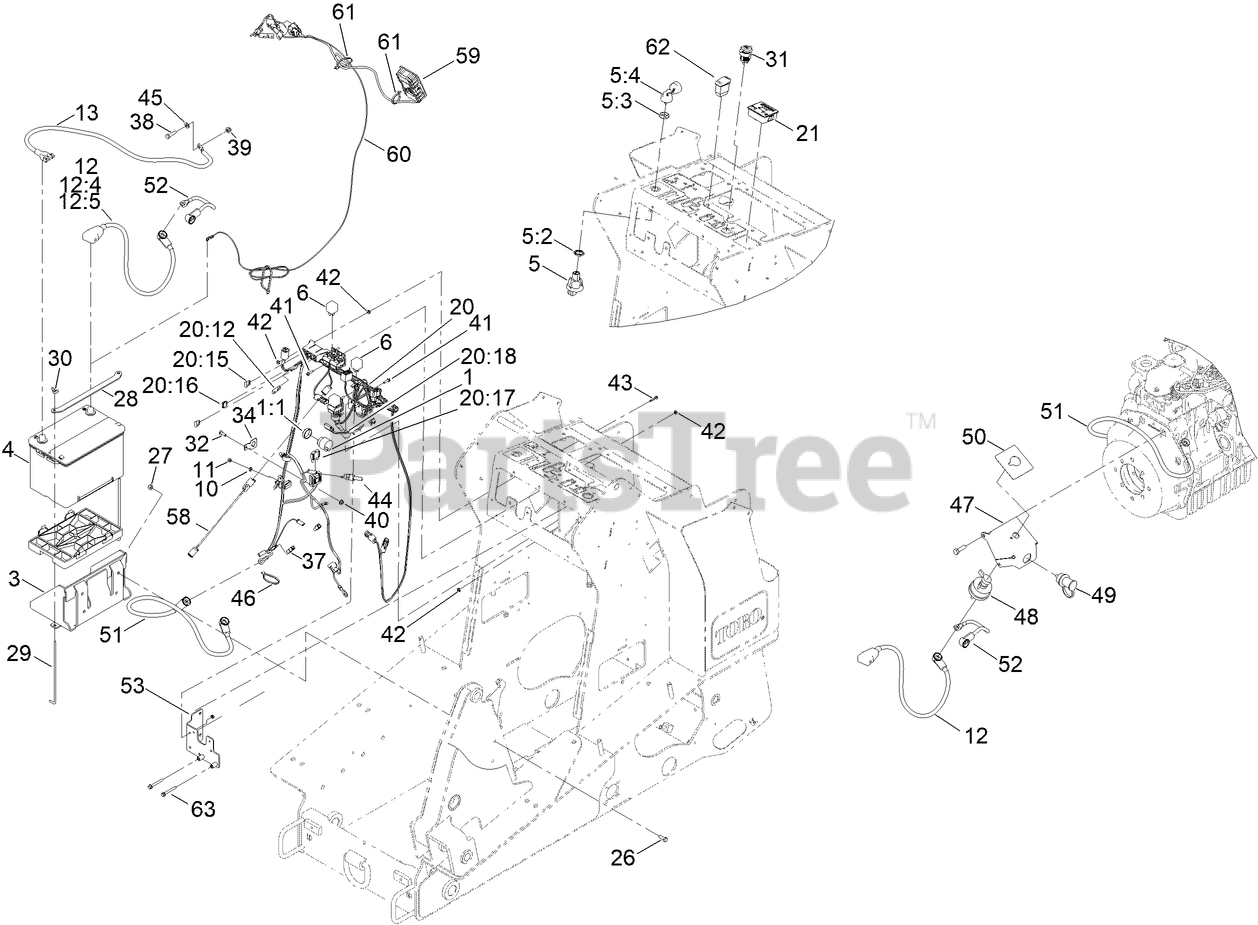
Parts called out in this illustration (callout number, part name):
1	AUDIO ALARM ASM
1:1	NUT-PLASTIC, KNURLED
3	TRAY-BATTERY
4	BATTERY
5	IGNITION SWITCH ASM
5:2	NUT-HEX
5:3	NUT-FACE
5:4	SET-KEY, IGNITION
10	WASHER-LOCK, SPRING
11	NUT-HEX
12	CABLE-BATTERY, POS ASM
12:4	BOLT-BATTERY CLAMP, 5/16-18 UNC
12:5	NUT-CLAMP, BATTERY
13	CABLE-NEGATIVE
20	HARNESS-WIRE, TX1000
20:15	FUSE-BLADE, 10 AMP
20:16	FUSE-BLADE, 15 AMP
20:17	FUSE-BLADE, 50 AMP
20:18	CAP-PLUG
21	MODULE-HOUR METER
26	SCREW-HH
27	NUT-LOCK, NI
28	STRAP-HOLD DOWN, BATTERY
29	ROD-HOLD DOWN, BATTERY
30	NUT-WING
31	RECEPTACLE-12V
32	SCREW-HH
34	CLIP-FUSE
37	HARNESS-LINK, FUSIBLE
38	SCREW-HH
39	NUT-HF, NI
40	NUT-HF
41	SCREW-HWH
42	NUT-KEPS
43	SCREW-HWHTF
44	SWITCH-TEMP
45	WASHER-PLAIN
46	TIE-CABLE
47	MOUNT-REMOTE TERMINAL
48	SWITCH-DISCONNECT, MASTER
49	STUD-JUMPER, POSITIVE
50	DECAL-BATTERY DISCONNECT
51	CABLE-BATTERY, POSITIVE
52	CABLE-BATTERY, POSITIVE
58	HARNESS-WIRE
59	M7L-LITE ZTR KIT ASM
60	HARNESS-WIRE, MACHINE ZTR
61	TIE-CABLE
62	SWITCH-INTERMITTENT
63	SCREW-HHF
